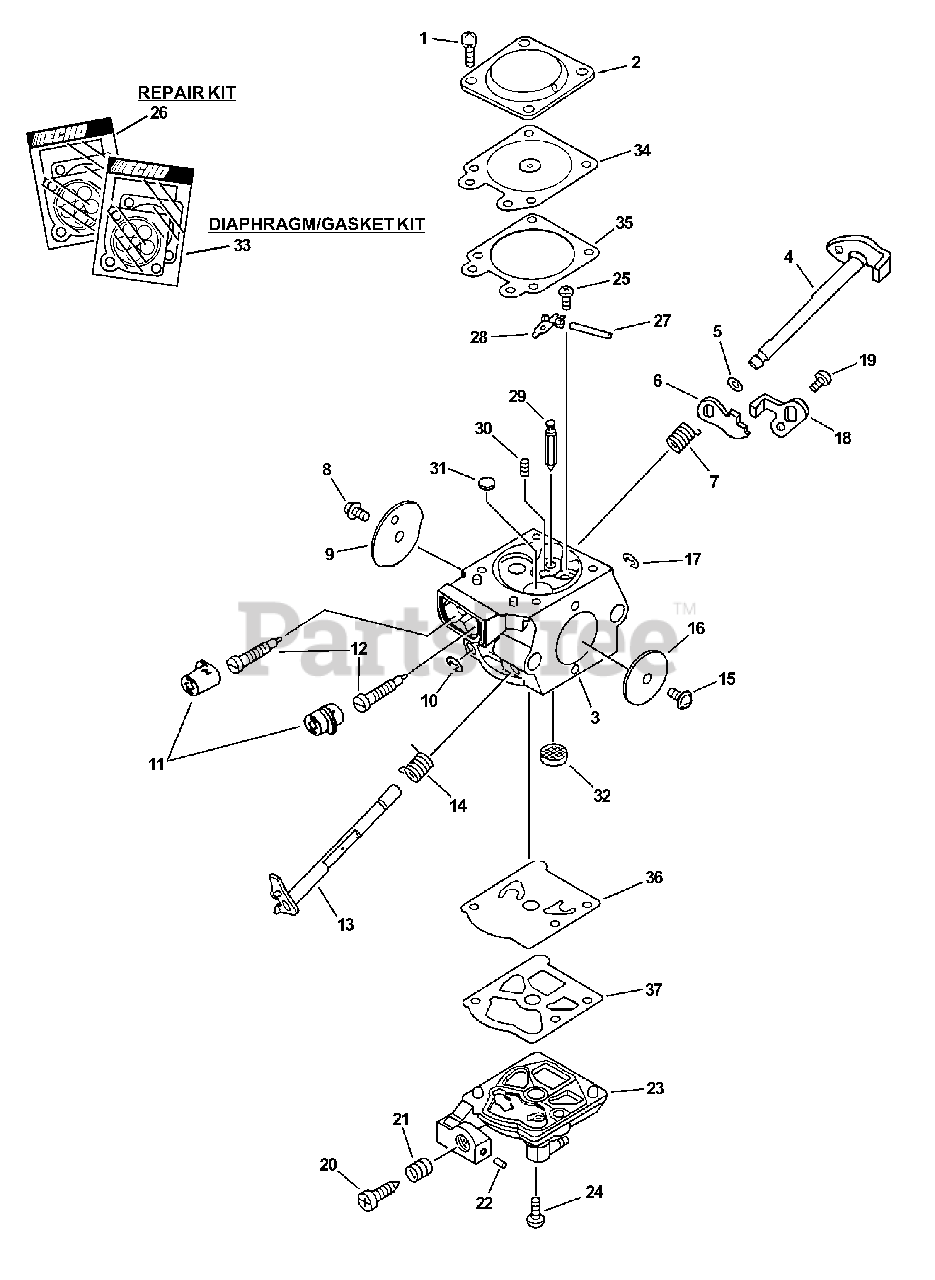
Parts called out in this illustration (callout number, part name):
2	COVER, METERING
3	BODY, CARBURETOR
4	SHAFT, CHOKE
6	LEVER, FAST IDLE
7	SPRING, CHOKE RETURN
9	VALVE, CHOKE
10	RING, RETAINING
11	CAP, LIMITER
12	NEEDLE - MIXTURE
13	SHAFT, THROTTLE
14	SPRING, THROTTLE RETURN
16	VALVE, THROTTLE
17	RING, RETAINING
18	LEVER, THROTTLE
20	SCREW, IDLE ADJUST
21	SPRING, IDLE ADJUST
23	COVER, PUMP
24	SCREW, PUMP COVER
25	SCREW, METERING LEVER PIN
26	REPAIR KIT
27	PIN, METERING LEVER
28	LEVER, METERING
29	VALVE, INLET NEEDLE
30	SPRING, METERING LEVER
31	PLUG, WELCH
32	STRAINER
33	DIAPHRAGM/GASKET KIT
34	DIAPHRAGM, METERING
35	GASKET, METERING
36	DIAPHRAGM, PUMP
37	GASKET, PUMP
